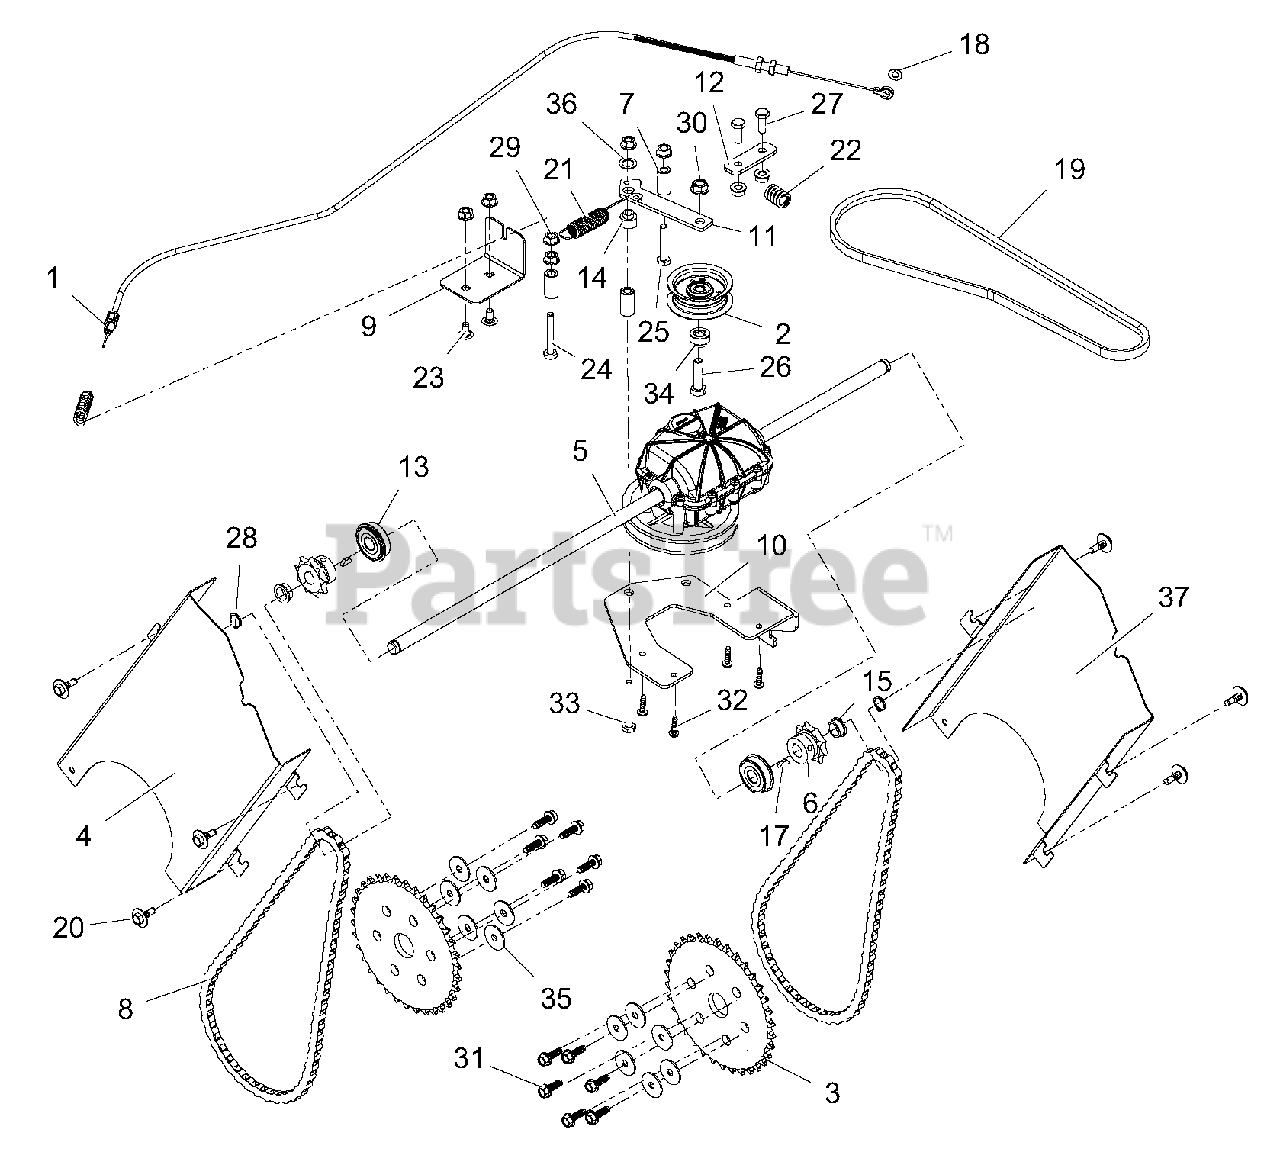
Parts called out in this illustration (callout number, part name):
1	CABLE, TRACTION - APV DRIVE
2	IDLER, FLAT - 2.00"
3	SPROCKET, DRIVE - 41 34T FLAT
4	GUARD, BELT - RIGHT APV
5	TRANS, DRIVE - GT MA502
6	SPROCKET,DRIVE - 41 9T #404KW
7	BSHG, SLV .265X.505X.995
8	CHAIN, ROLLER - #41 64 PITCHES
9	MOUNT, CABLE - APV TRACTION
10	MOUNT, TRANSMISSION - APV
11	ARM, IDLER - APV BELT DRIVE
12	PLATE, RETAINER - APV TRANS
13	BRG-BALL .50X1.38X.438 SEALED
14	BSHG,FLG .263X.393X.18X.625
15	BSHG,FLANGE .500X.625X.270X.75
17	KEY-WDRF .125X.50X.20 (HRDEND)
18	NUT-PUSH .25X.50 O.D.
19	V-BELT, 3L-WRAPPED
20	SCR-TAP .25-20X.5 CAPTIVE
21	SPRG, EXTENSION
22	SPRG, COMPRESSION
23	@BLT-RDHDSQNK .25-20X.50 G5YZ
24	@BLT-HEX .25-20X1.75 GR5 YWZC
25	@BLT-HEX .25-20X1.50 GR5 YWZC
26	@BLT-HEX .31-18X1.25 GR5 YWZC
27	@BLT-HEX .25-20X.75 GR5 YWZC
28	RG-RTNG-EXT .500X.050 (SNAP)
29	@NUT-LK-TOP-FLG .25-20 YWZC
30	@NUT-LK-TOP-FLG .31-18 YWZC
31	SCR-HEX .25X14-.75
32	SCR-TAP 10-14X.75PLSTITE BLKOX
33	@BLT-HEX .25-20X2.00 GR5 YWZC
34	SPCR, BRG .315X.500X.481X.281
35	WSHR-FL-STL .281X1.000X.063
36	WSHR-FIBER .437X.656X.032
37	GUARD, CHAIN - LEFT APV
